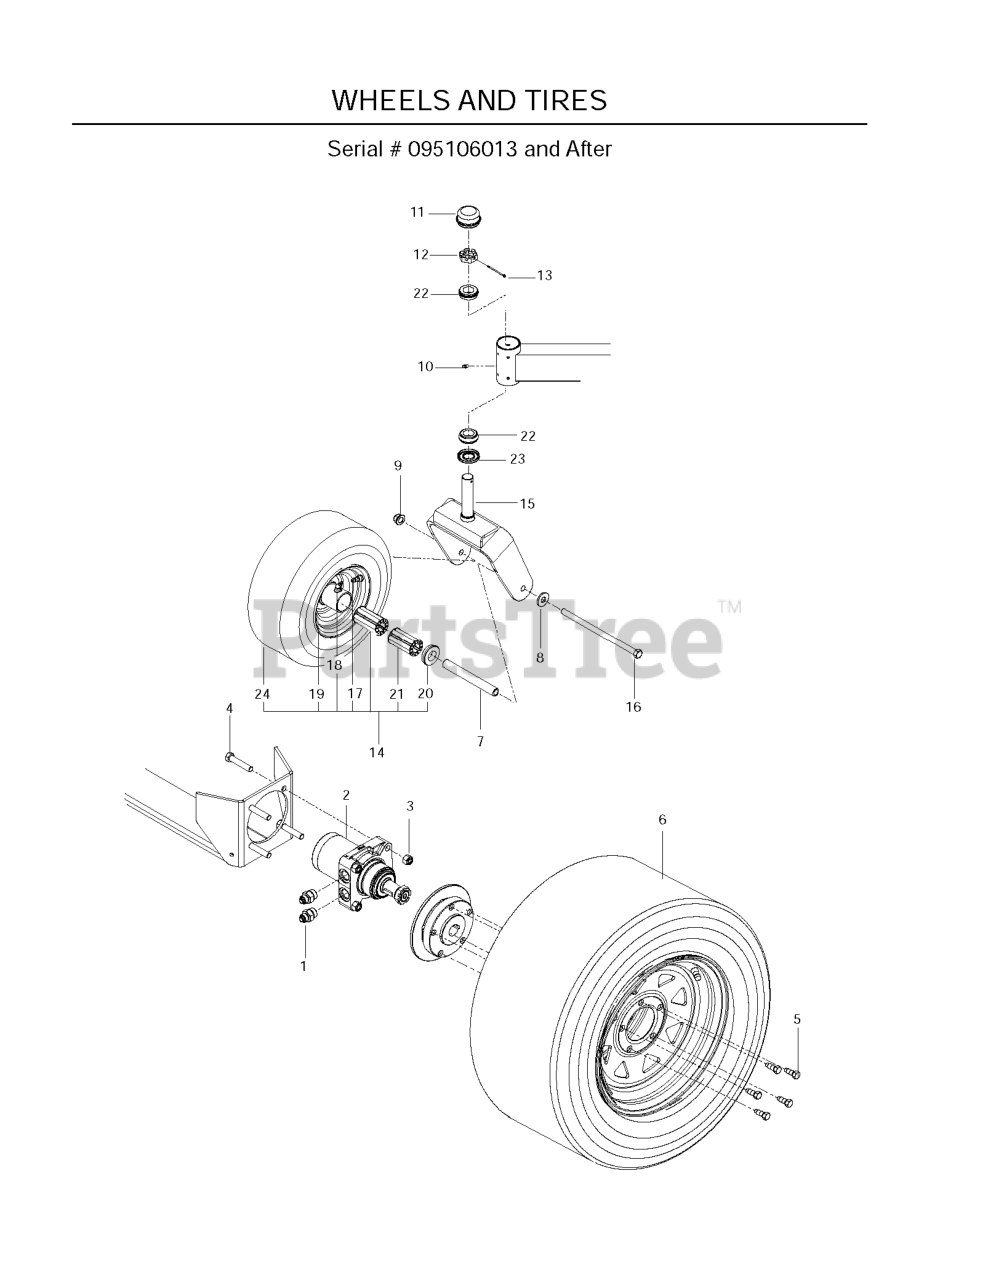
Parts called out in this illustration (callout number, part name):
1	CONNECTOR, STRAIGHT
2	WHEEL MOTOR, TJ
3	NUT 1/2-13 HEX NYLOC ZD
4	HCS 1/2C X 2 3/4
6	WHEEL.R.TS.23X10.5-12.C.MS
7	SPACER, PIVOT
8	WASH USS FLAT 1/2
9	NUT, 1/2-13 HEX FLG NYLOC ZD
11	GREASE CAP
12	NUT 1"C HEX SLOTTED
13	COTTER PIN 1/8 X 2
14	TIRE.ASSEM.CASTER.13X6.5-6.SIL
15	YOKE.CASTER.ORANGE
16	HEX SCREW 1/2-13 X 9.5 GR5
17	VALVE STEM TR-412
18	ZERK
19	WHEEL.6X4.50.CASTER.SILVER
20	BEARING RETAINER
21	ROLLER BEARING-CAGED 3 1/4'
22	TAPERED ROLLER BRG
24	TIRE.13X6.50-6.4.PLY
